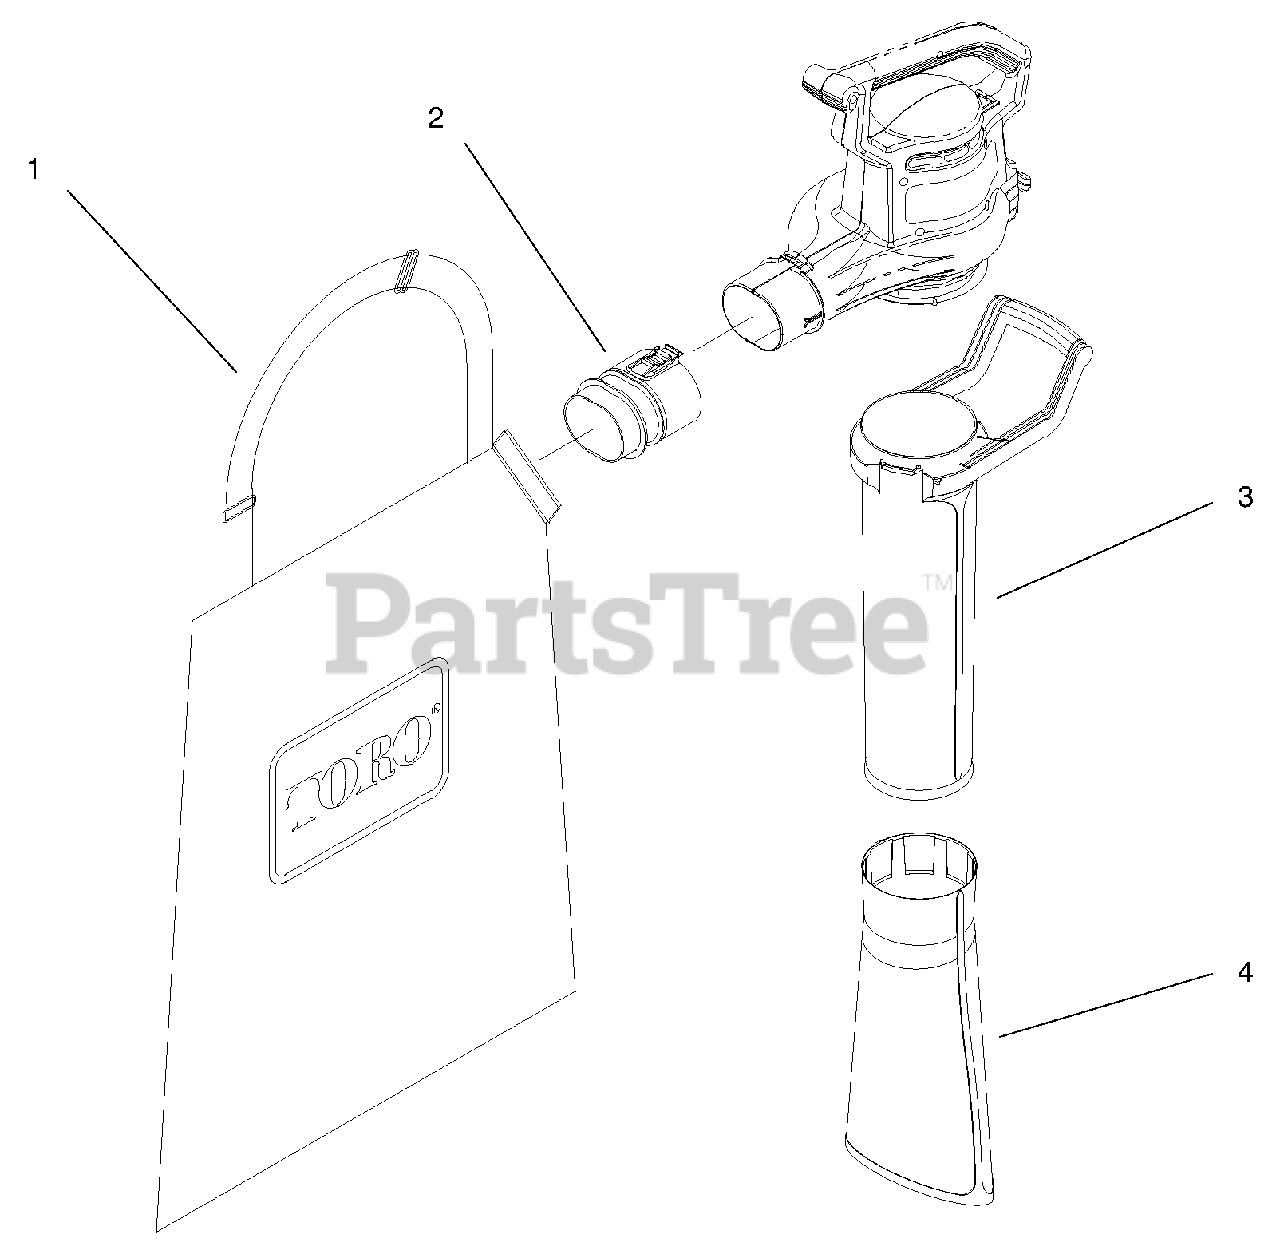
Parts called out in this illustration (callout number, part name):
1	Bag
2	Tube-Bag Inlet
3	Tube-Vac Upper
4	Tube-Vac Lower
